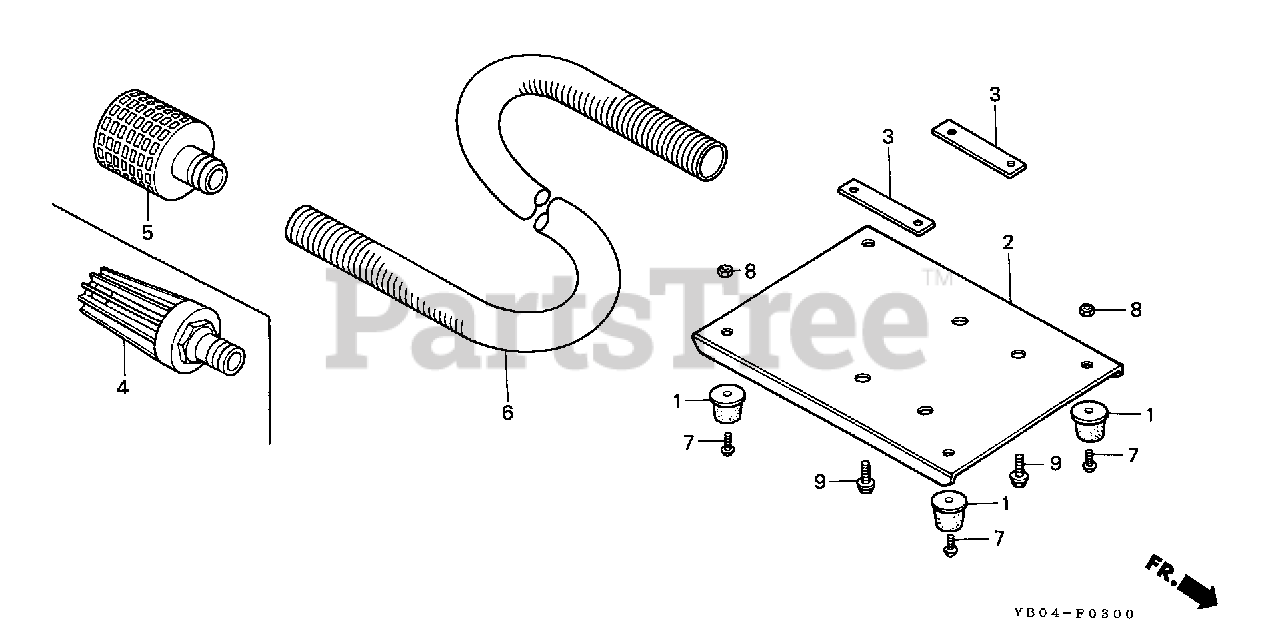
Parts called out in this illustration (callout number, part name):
1	RUBBER (LOWER)
2	BED, FRAME
3	PLATE, BASE
5	STRAINER
6	HOSE, SUCTION (1.5X5)
7	SCREW, PAN (6X10)
8	NUT, HEX. (6MM)
9	BOLT, FLANGE (8X20)
